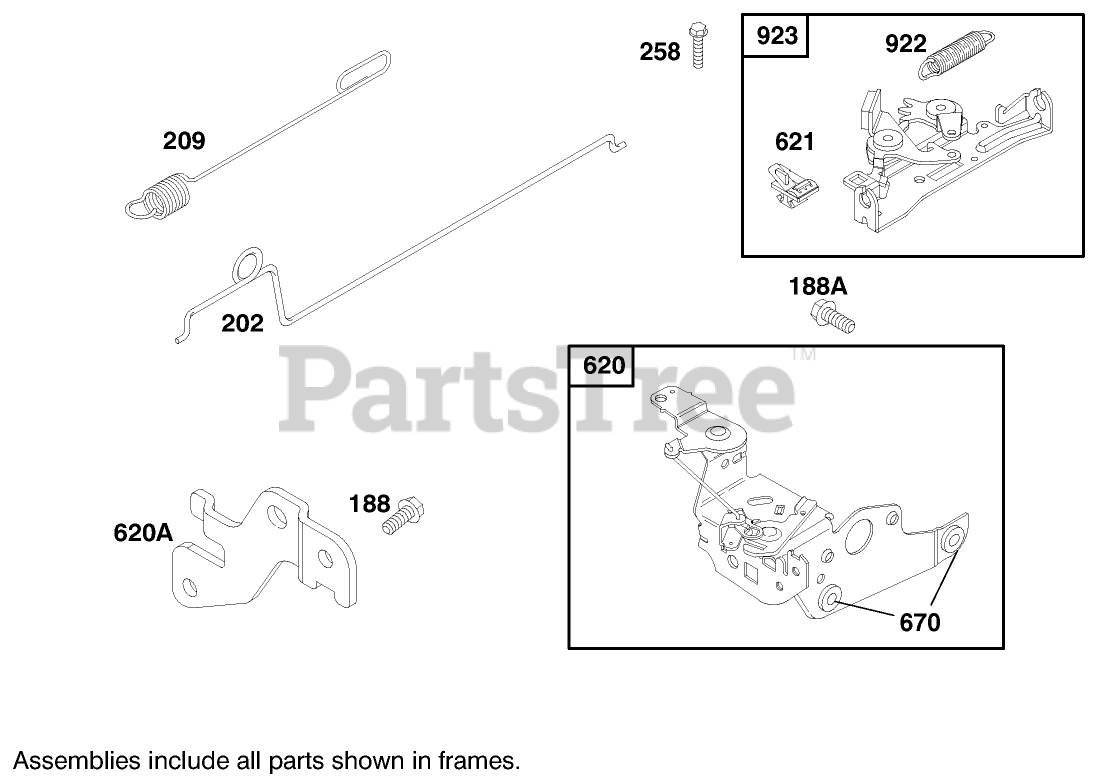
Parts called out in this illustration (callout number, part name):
188	Screw-Hex.
188A	Screw-Hex.
202	Link-Govemor
209	Spring-Governor
258	Screw-Sem
620	Bracket-Carburetor
670	Spacer
922	Brake Spring
923	Brake
